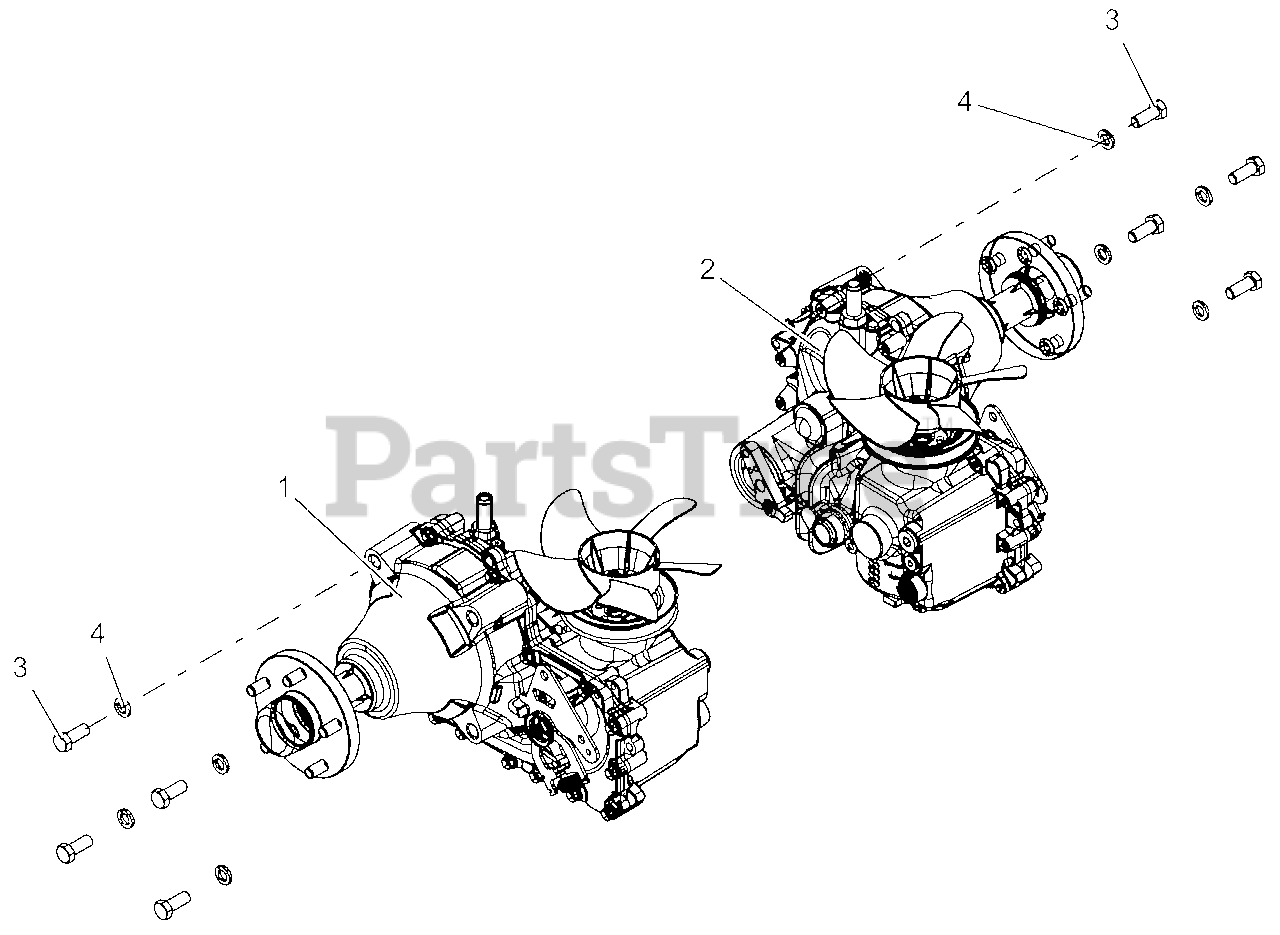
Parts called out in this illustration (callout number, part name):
1	TRANS, R.H. HG ZT-5400
2	TRANS, LH HG ZT-5400
3	BLT-HEX .50-13X1.25 GR5 YWZC
4	WSHR-LK .50X.125 REG YWZC
